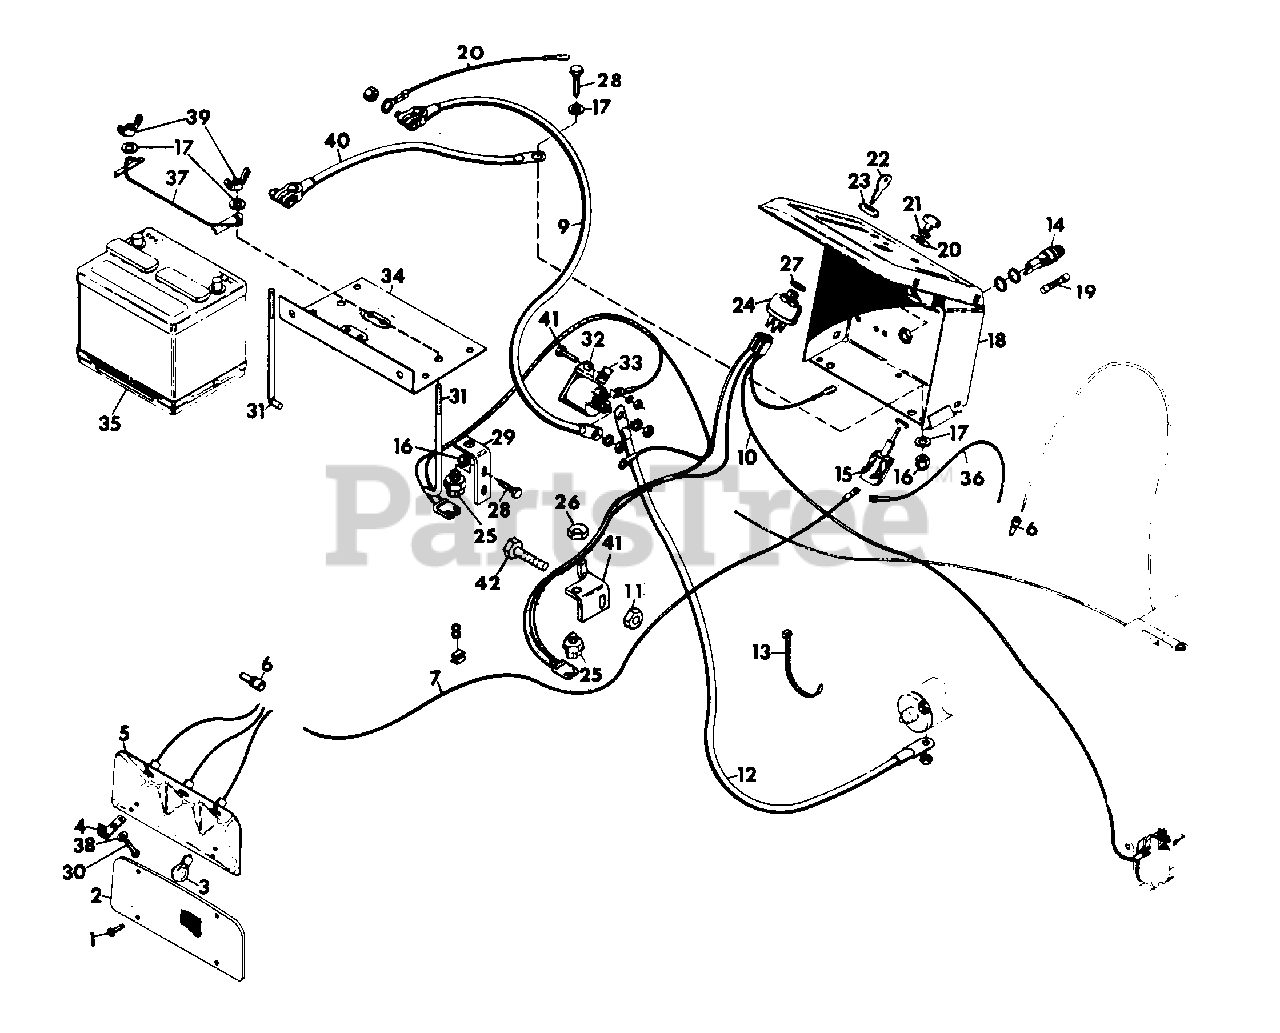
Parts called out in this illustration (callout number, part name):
1	SCREW, MACH 10-24X.50 PAN HD C-RECESS
2	PANEL, FRONT LIGHT
3	LAMP, NO. 1073
4	CLIP, LIGHT MTG.
5	ASSEMBLY, LAMP REFLECTOR
6	NUT, WIRE
7	WIRE, HEADLIGHTS
8	CLIP, WIRE
9	CABLE, BATTERY TO MAGNETIC SWITCH
10	HARNESS, WIRING 16 HP B&S
11	NUT, LOCK 3/8-16
12	CABLE, STARTER
13	TIE, CABLE
14	FUSE, PANEL
15	SWITCH, LIGHT
16	NUT, LOCK 1/4-20
17	WASHER, FLAT, .281X.625X.065
18	PANEL, INSTRUMENT
19	FUSE, 30 AMP ACC-30
20	WIRE, INSTRUMENT PANEL
21	NUT, SPECIAL
22	KEY, IGNITION SWITCH
23	NUT, JAM 9/16-24
24	SWITCH, IGNITION
25	SWITCH, INTERLOCK
26	NUT, STAMPED 9/16-18
27	WASHER, LOCK INT. TOOTH
28	BOLT, HEX 1/4-20X.875
29	BRACKET, SWITCH
30	SCREW, MACH. 10-24 PAN HD
31	HOOK, BATTERY
32	SWITCH, MAGNETIC
33	NUT, SPEED 1/4-20
34	TRAY, BATTERY
35	BATTERY, 12V
36	WIRE, HEADLIGHT
37	BRACKET, BATTERY HOLD DOWN
38	WASHER, FLAT .188X.562X.049
39	NUT, WING 1/4-20 WASHER INSERT
40	CABLE, NEGATIVE BATTERY
41	BRACKET, INTERLOCK SWITCH
42	BOLT, HEX 3/8-16 X 1.25
NS	WASHER, LOCK 1/4 EXT TOOTH TYPE A
NS	BOOT, BATTERY CABLE
